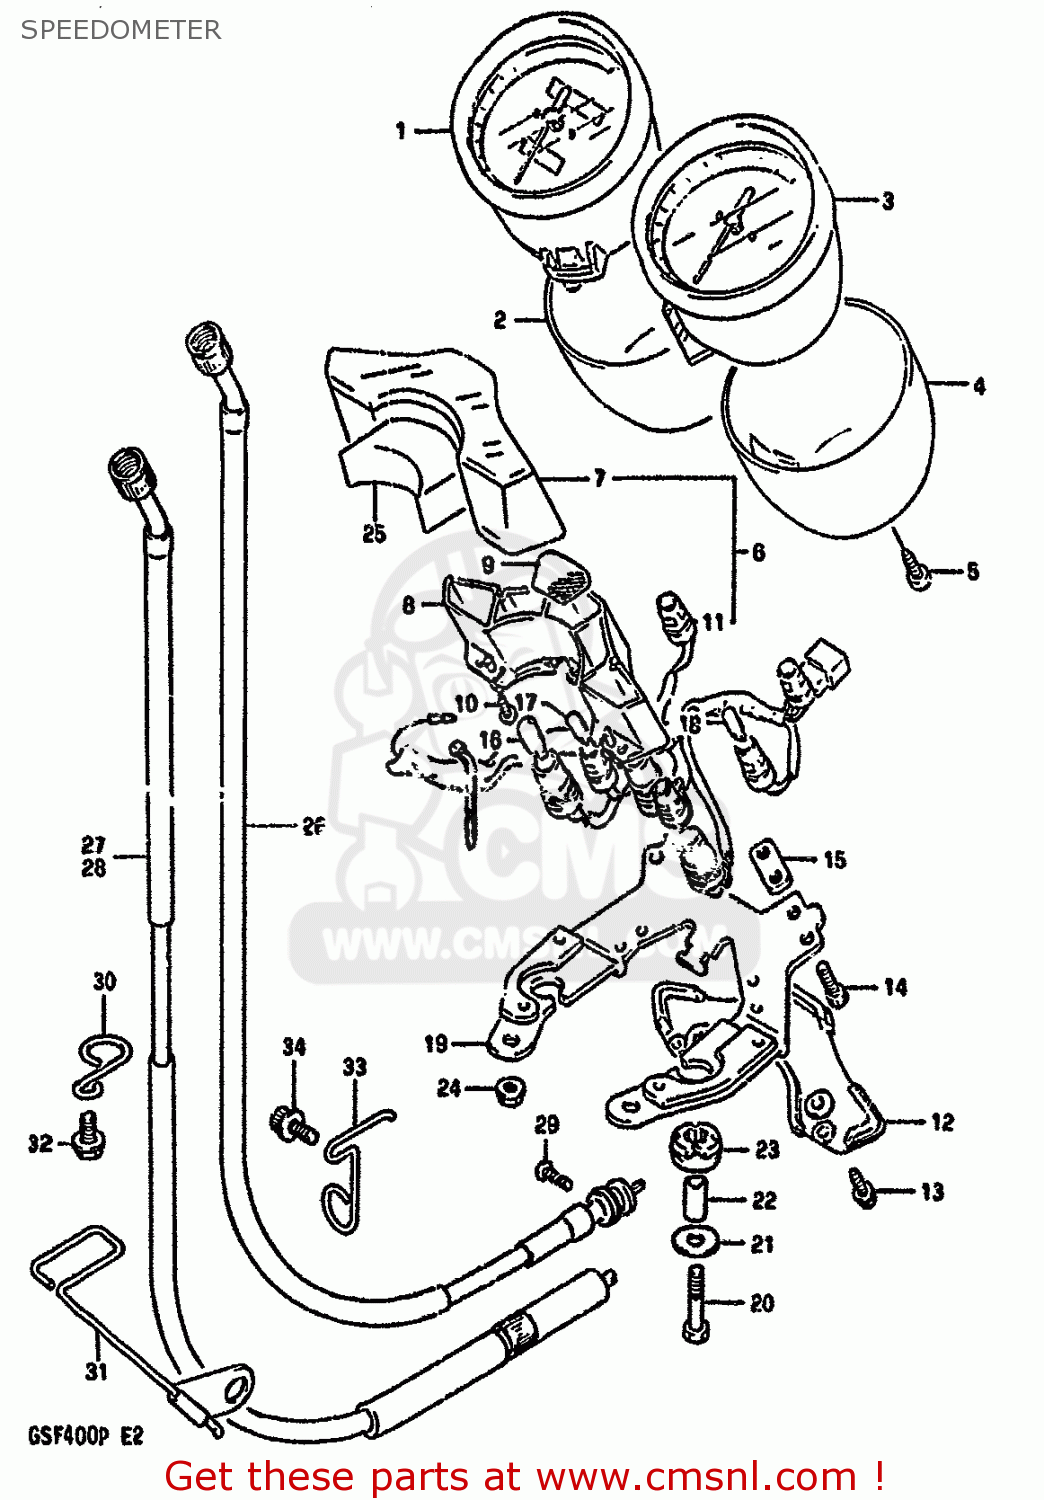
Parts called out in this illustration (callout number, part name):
1	SPEEDOMETER
2	LWR CASE,SPEEDOMETER
3	TACHOMETER
4	LOWER CASE,TACHOMETER
5	SCREW
6	BOX PILOT
7	UPR CASE
8	INNER CASE
9	LENS SET
10	SCREW
11	SOCKET
12	LOWER CASE
13	SCREW
14	BOLT
15	PLATE
16	BULB(12V3.4W,T10,BF175-01450A)
17	BULB(12V3W,WB371,T7)
18	BULB(12V1.7W,WB372,T7)
19	BRACKET,METER
20	BOLT
21	WASHER
22	SPACER
23	CUSHION
24	NUT
25	CUSHION,PILOT LAMP
26	CABLE ASSY,SPEEDOMETER
27	CABLE ASSY,SPE
28	CABLE ASSY,SPEEDOMETER
29	SCREW
30	CLAMP,SPEEDOMETER CABLE
31	CLAMP,SPEEDOMETER CABLE
32	BOLT
33	CLAMP,SPEEDOMETER CABLE
34	BOLT
